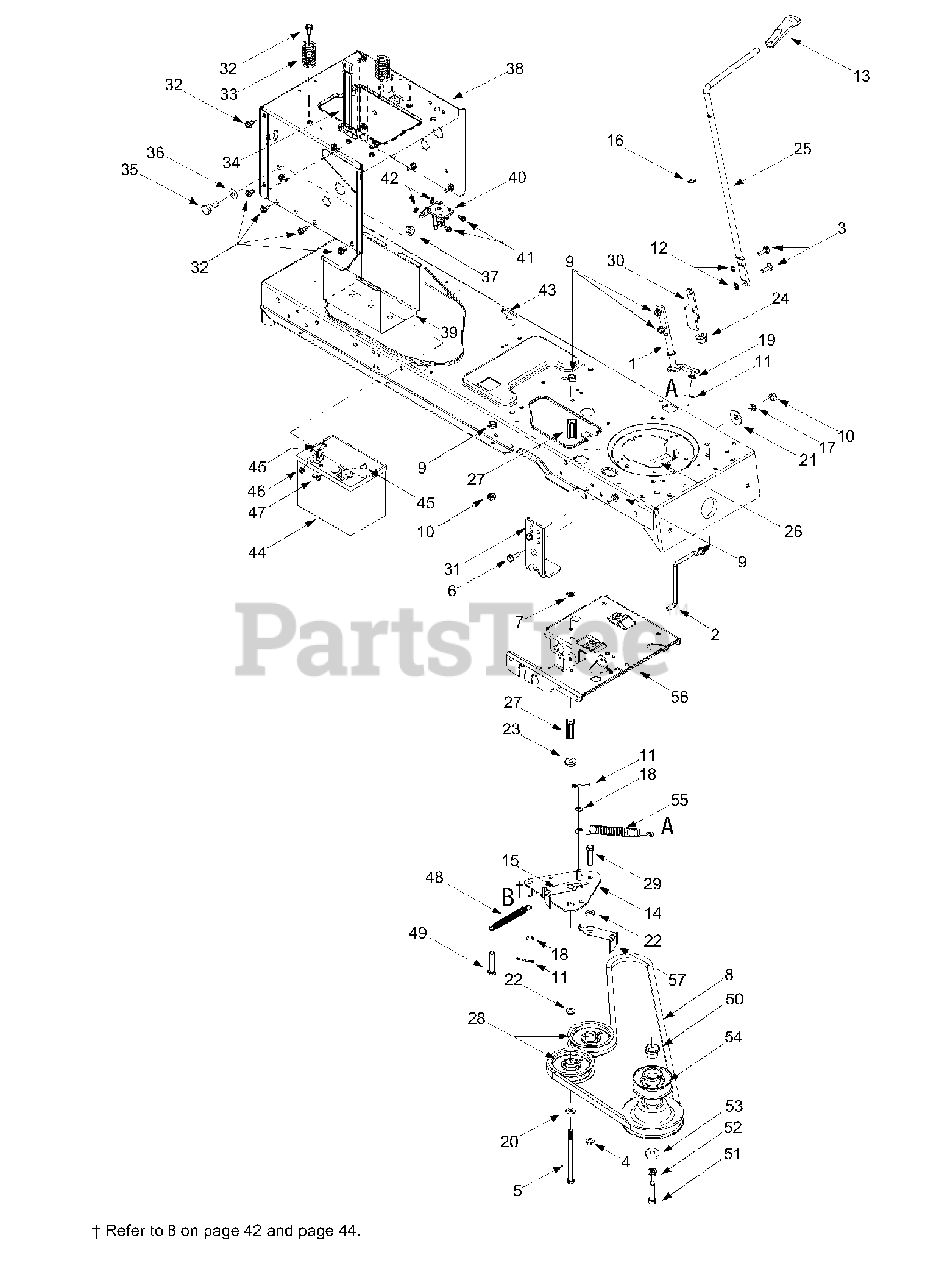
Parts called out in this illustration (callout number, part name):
1	PTO Engage Lever Assembly
2	Belt Keeper Rod
3	Carriage Screw, 5/16-18 x 1.00
4	Flange Lock Nut, 3/8-16
5	Hex Cap Screw, 3/8-16 x 5.5
6	Hex Head Washer Screw, 5/16-18 x .875
7	Push Nut, 3/8
8	PTO Belt (Models w/ 46-inch deck)
9	Flange Lock Nut, 5/16-18
10	Hex Nut, 5/16-18
11	Cotter Pin, 1/8 x 1.25
12	Speed Nut, .3125
13	PTO Knob
15	Belt Guard
16	Flat Washer, .510 x .750 x .033
17	Lock Washer, 5/16
18	Flat Washer, .385 x .62 x .063
19	Flat Washer, 5/16
20	Flat Washer, .406 x .875 x .059
21	Bell Washer, .39 x 1.13 x .062
22	Flat Washer, .407 x .812 x .135
23	Shoulder Spacer, .380
24	Hex Split Flange Bearing, .5
26	Belt Keeper Rod
27	Spacer, 3/8 x 1.54
28	Idler Pulley, 3.5
29	Hex Cap Screw, 3/8-16 x 1.75
32	Self Tapping Screw, 5/16-18 x .625
33	Compression Spring, 1.28 x 3.5
34	Battery Strap
35	Shoulder Screw, .625 x .5, 7/16-20
36	Bell Washer, .45 x 1.0 x .062
37	Flange Lock Nut, 7/16-20
41	Self Tapping Screw, 1/4-20 x .5
42	Lock Washer, 1/4
45	Hex Cap Screw, 1/4-20 x .62
46	Hex Sems Nut, 1/4-20
47	Wing Nut, 1/4-20
48	Extension Spring, .50 x 5.0
49	Hex Cap Screw, 5/16-18 x 1.75
50	Spacer Cup
51	Hex Head Cap Screw, 7/16-20 x 1.25
52	Lock Washer, 7/16
53	Flat Washer, .450 x 1.25
54	Engine Pulley, 3.56 OD x 5.56
55	Extension Spring, .75 x 6.75
57	Belt Guard
